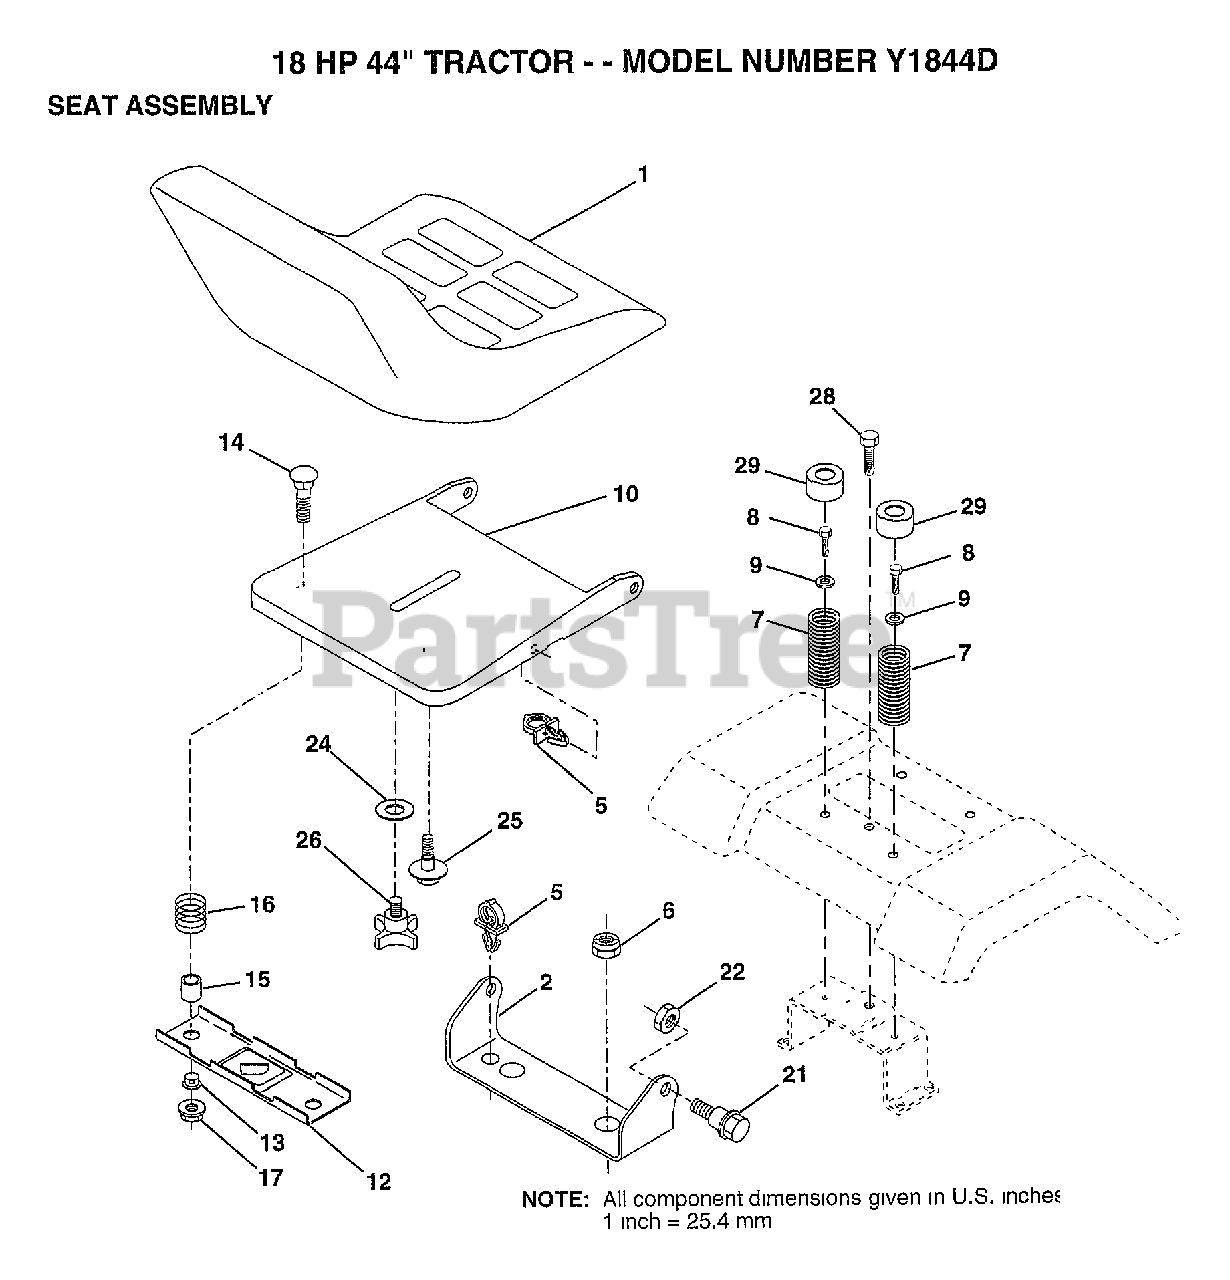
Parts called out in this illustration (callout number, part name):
2	BRACKET PVT SEAT
5	CLIP PUSH - IN
7	SPRING COMPRESSIO
8	SCREW LT
9	WASHER
12	BRKT SWITCH
13	BUSHING
15	SPACER SPLIT
16	SPRING COMPRESSED
21	BOLT.SHLD.5/16-18
24	WASHER
25	"BOLT,SHOULDER"
26	"KNOB 1/2"" YT"
28	SCREW LT
29	CAP SPRING
